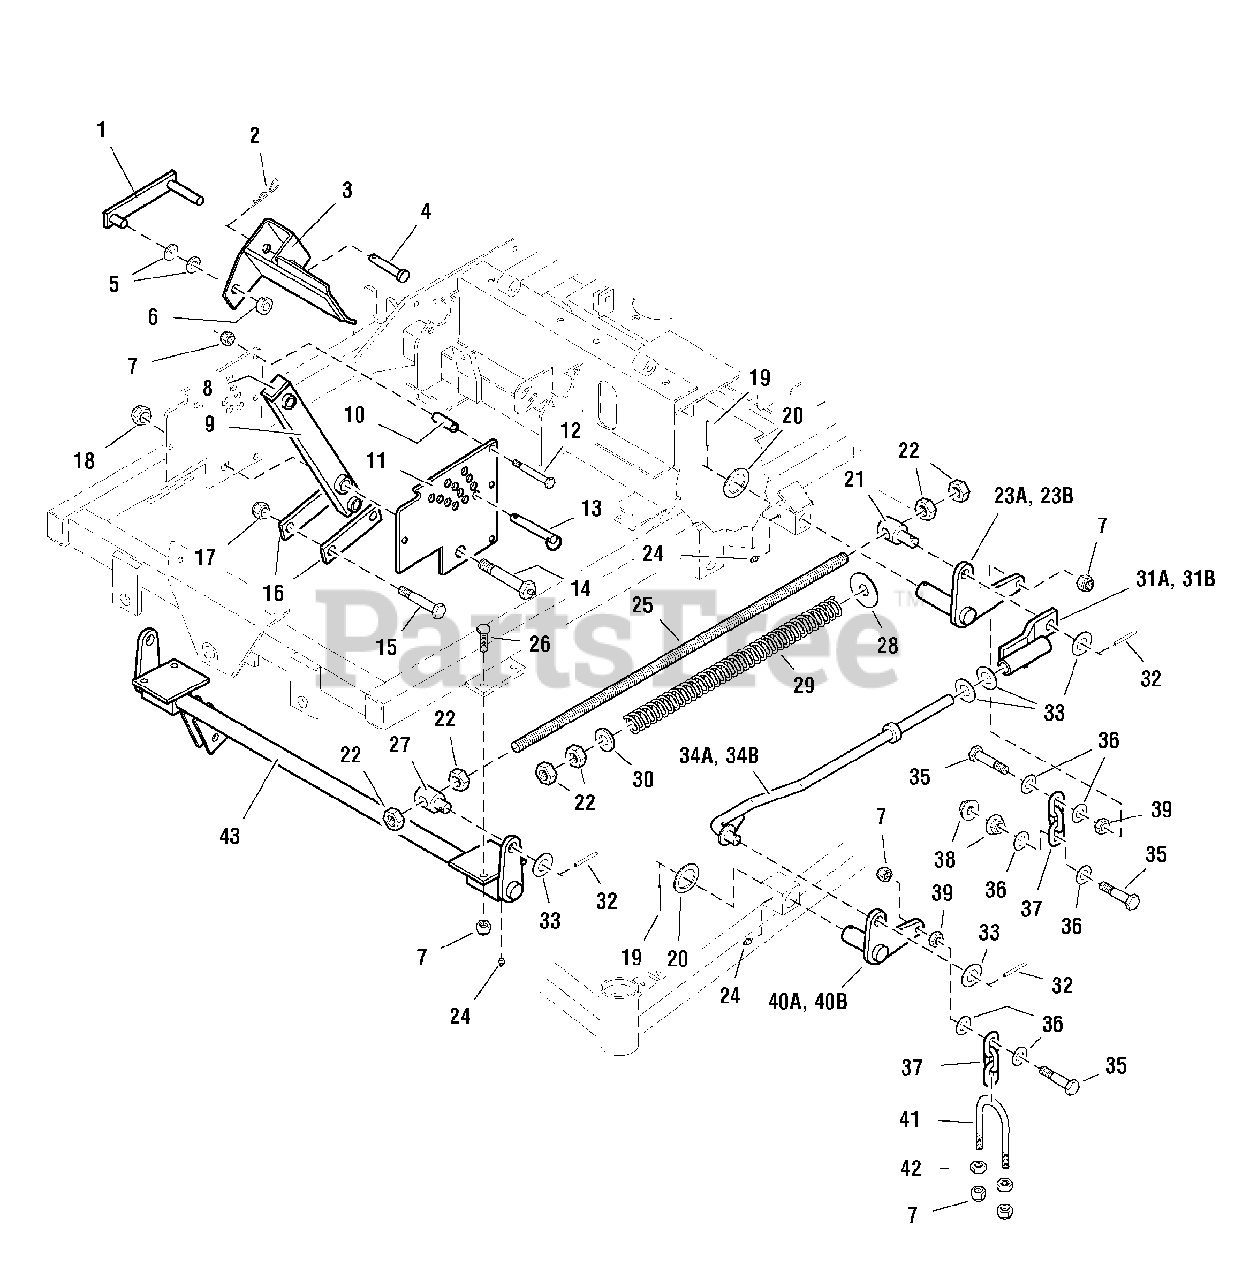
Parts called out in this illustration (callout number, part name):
1	DECK LIFT LOCK
2	HAIRPIN CLIP
3	DECK LIFT PEDAL
4	PIN, Clevis, 1/2 x 2-1/2
5	WASHER, 1/2
6	COLLAR, Split, 1/2
7	NUT, Hex, Nylon Lock, 3/8-16
9	ARM, Deck Lift Pivot
10	SPACER, .38 x .50 x 1.56
11	DECK HEIGHT PLATE
12	CAPSCREW, Hex Hd, 3/8-16 x 2-3/4
13	PIN, 1/2 x 3
14	LIFT PIVOT BOLT
15	CAPSCREW, Hex Hd, 1/2-20 x 3
16	LINK, Deck Lift
17	NUT, Hex, Nylon Lock, 1/2-20
18	NUT, Hex Jam, Nylon Lock, 5/8-11
19	PIN, Roll, 3/16 x 1-1/2
21	SPRING ROD PIVOT
22	NUT, Hex, 5/8-11
23A	DECK LIFT PIVOT-LH
24	GREASE FITTING
26	CAPSCREW, Hex Hd, 3/8-16 x 1-1/4
27	SPRING ROD PIVOT
28	WASHER, USS, 5/8
29	DECK LIFT SPRING
30	SPACER, .63 x 1.06 x .23
31A	DECK LIFT OFFSET LINK-LH
32	PIN, Spring, 3/16 x 1-1/4
33	WASHER, 5/8
34A	DECK LIFT ROD-LH
35	CAPSCREW, Hex Hd, 3/8-16 x 1-3/4
36	WASHER, 3/8
37	CHAIN, 3 Links
38	NUT, Hex, Serrated Flange, 3/8-16
39	NUT, Hex, Jam, 3/8-16
40A	DECK LIFT PIVOT-LH
42	NUT, Hex, 3/8-16
43	DECK LIFT SHAFT & MOUNT ASSEMBLY
